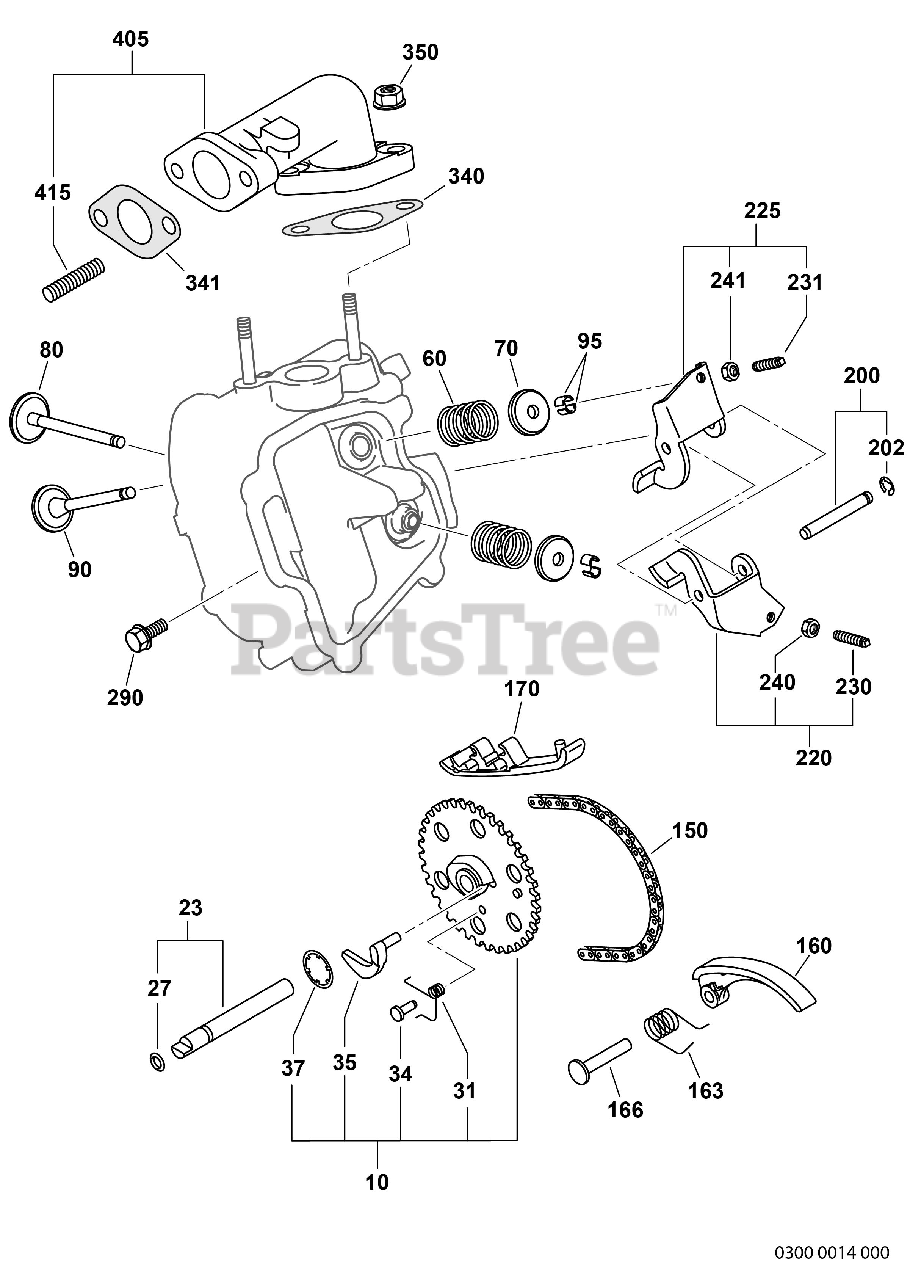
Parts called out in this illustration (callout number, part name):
23	PIN(CAM SHAFT)CP
70	SPRING RETAINER
150	TIMING CHAIN CP
163	SPRING(TENTIONER)
166	PIN(TENTIONER)
220	ROCKER ARM(IN) AY
225	ROCKER ARM(EX) AY
340	GASKET(MUFFLER)
341	GASKET CP (MUFFLER)
405	EXHAUST PIPE CP
